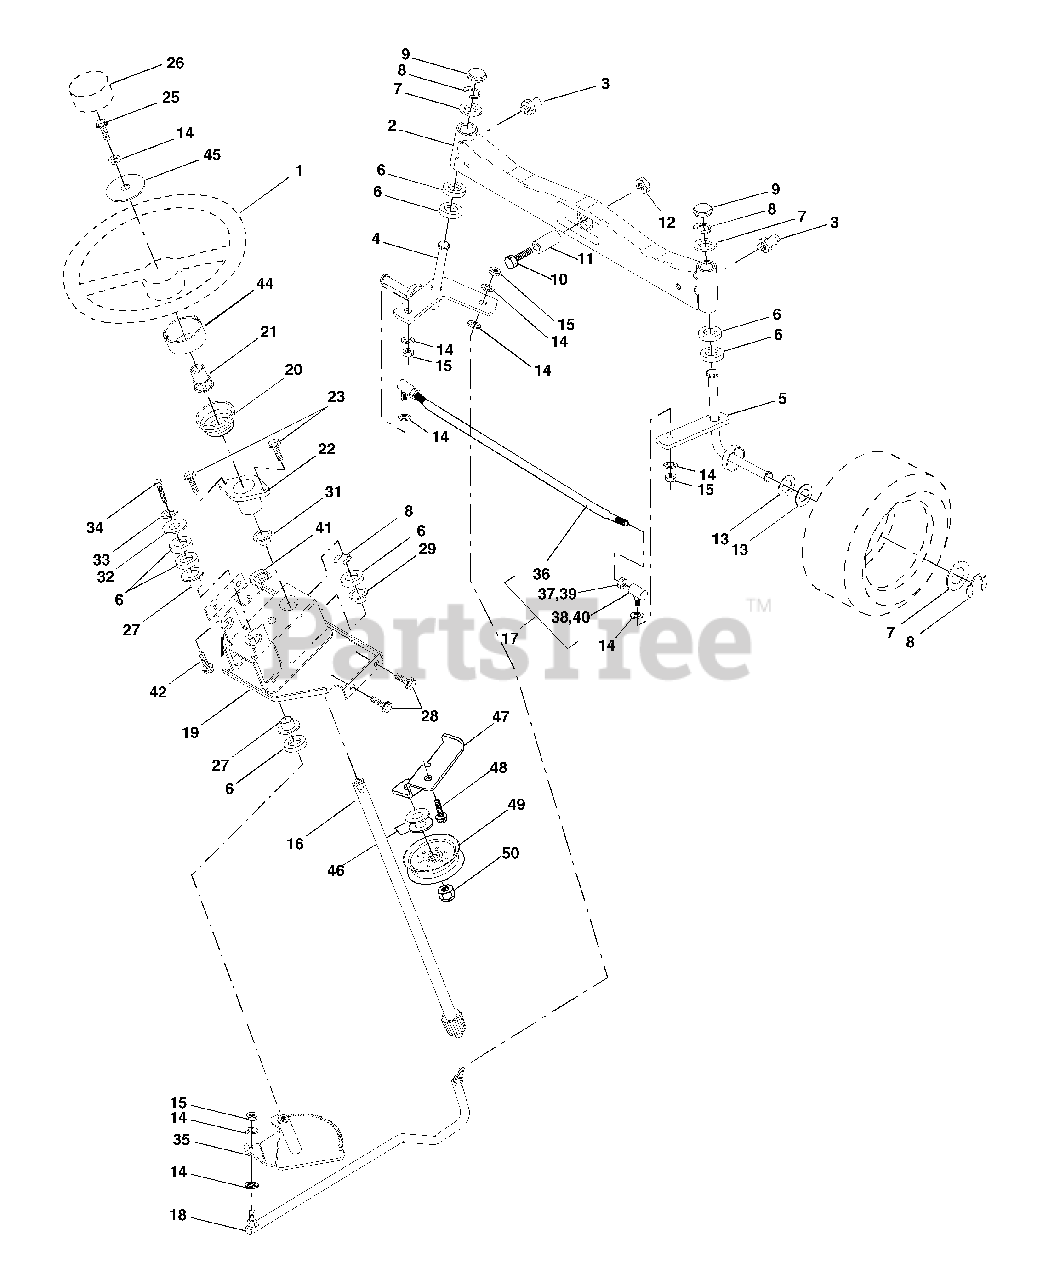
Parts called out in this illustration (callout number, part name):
1	Wheel, Steering
2	Axle Asm., Front
3	Fitting, Grease
4	Spindle Asm, LH
5	Spindle Asm., RH
6	Bearing, Race Thrust Harden
7	Washer 25/32 x 1-5/8 x 16 Ga.
8	Ring, Klip #T5304-75
9	Cap, Spindle
10	Bolt, Fin Hex 5/8-11 x 2-3/4
11	Spacer Brg Axle Front 1.570
12	Nut, Lock Flange 5/8-11 Unc
13	Washer 25/32 x 1-1/4 x 16 Ga.
14	Washer, Lock Hvy Hlcl Spr 3/8
15	Nut Lock Center 3/8-24 Unf
16	Shaft Asm., Steering
17	Rod Asm., Tie Ball J Ball Vgt
18	Draglink, Ball Joint Solid Vgt
19	Support Asm., Steering Vgt
20	Boot Steering
21	Adapter, Wheel Steering
22	Bushing, Strg.
25	Bolt, Fin Hex 3/8-16 x 1 Gr. 5
26	Cap , Wheel Steering
27	Bearing, Col. Strg.
28	Screw 3/8-16 x 3/4
29	Bearing, Flange
31	Bushing, Nyliner Snap
32	Washer 11/32 x 1 x 10 Ga.
33	Washer, Lock Hvy Hlcl Spr 5/16
34	Bolt, Hex Hd 5/16-18 x 3/4
35	Gear, Sector Steering
36	Tie Rod
37	Jam Nut RH Thread
38	Joint Asm. Ball RH Thread
39	Nut Hex Jam 3/8-24 UNF LH
40	Joint Asm Ball LH
41	Bracket Switch Inerlock VGT97
42	Screw 5/16-18 x 1/2
44	Extension Steering Premium
45	Washer 13/32 x 1-1/20 x 11 Ga.
46	Washer FLat 13/32 x 1/10 Ga.
47	Bracket Asm. Idler
48	Screw 3/8-16 x .75
49	Pulley Idler Flat
50	Nut Lock Flg 3/8-16 Unc
